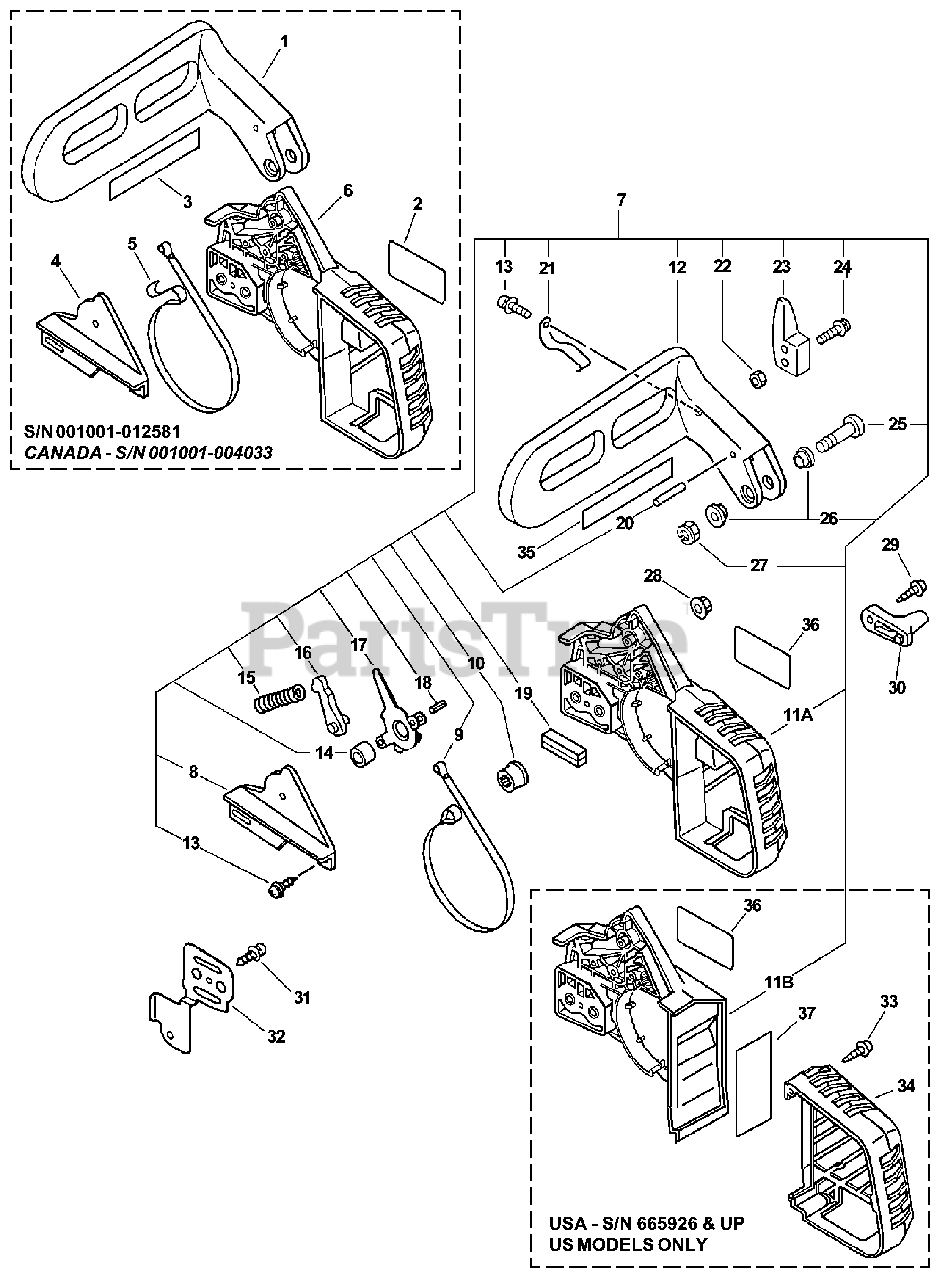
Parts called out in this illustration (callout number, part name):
1	LEVER, BRAKE
2	LABEL - MODEL
3	LABEL - BAR & CHAIN -- US
3	LABEL - BAR & CHAIN -- CANADA
4	COVER, BRAKE
5	BAND, BRAKE
6	GUARD, SPROCKET
7	CHAIN BRAKE ASSY
8	COVER, BRAKE - GRAY
9	BAND, BRAKE
10	ADJUSTER, BRAKE BAND
11A	GUARD, SPROCKET
11B	GUARD, SPROCKET
12	LEVER, BRAKE - ORANGE
13	SCREW - 4X12 -- TAPPING
14	SPACER - 8
15	SPRING, BRAKE
16	STOPPER, BRAKE
17	LEVER, BRAKE
18	PIN - SPRING -- 4X8
19	SEAL
20	ROLLER - 4X23.8
21	SPRING, RETURN
22	NUT - 4
23	WEIGHT, BRAKE
24	SCREW - 4X20
25	SCREW - 5X32
26	SPACER
27	LOCKNUT - 5
28	NUT - 6 -- FLANGE
29	SCREW - 5X20 -- TAPPING
30	CATCHER, CHAIN
31	SCREW - 4X10
32	PLATE, GUIDE - OUTER
33	SCREW - 5X20 -- TAPPING
34	COVER, EXHAUST
35	LABEL - MODEL CS-3450
36	LABEL - BAR & CHAIN -- US
36	LABEL - BAR & CHAIN -- CANADA
37	DEFLECTOR, HEAT
